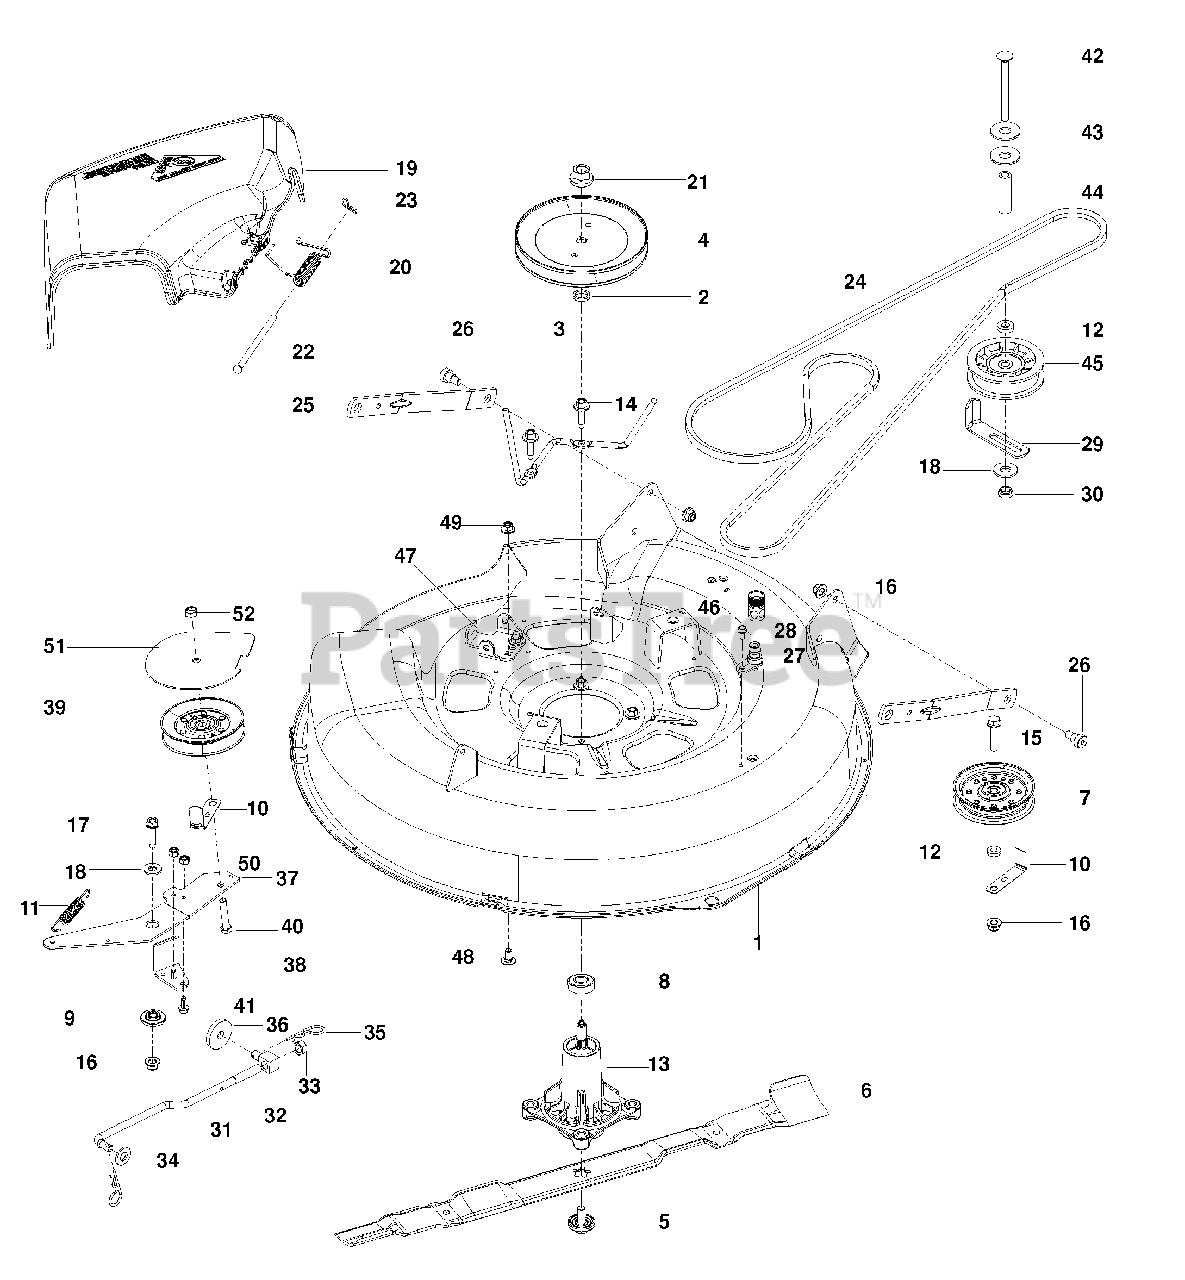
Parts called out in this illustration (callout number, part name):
1	DECK w/ DECALS ORG
2	WASHER/SPACER
3	KEEPER, BELT
4	PULLEY, MANDREL
5	BOLT/WASHER ASSY
6	BLADE, MOWER/MULCH
7	PULLEY, IDLER
8	BEARING, BALL
9	SPACER RETAINER
10	KEEPER, BELT
11	SPRING RETURN
12	WASHER 3/8 x 3/4
13	MANDREL ASSY
14	SCREW 5/16-18 WASHER HD
15	BOLT 3/8-16 x 1 3/4 WHIZLK
16	NUT 3/8-16 FLANGE NYLOC
17	BOLT 3/8-16 x 1 1/2 THD FRM
18	WASHER 3/8 FLT STD
19	CHUTE, DISCHARGE
20	SPRING, TORSION
21	NUT 9/16 TOP CENTER LOCK
22	PIN, CLEVIS
24	BELT, DECK
25	ARM, DECK SUSPENSION
26	BOLT 3/8-16 x 3/8 SKT HD
27	WASHOUT PORT
28	BOLT 1/4-20 x 1/2 HWST
29	GUIDE, BELT
30	NUT 3/8-16 HEX JAM NYLOC
31	LINK, SUSPENSION
33	NUT 7/16-20 HEX NYLOC
34	WASHER 1/2 SAE
36	WASHER 1 3/4 x 1/4 HEAVY
37	ARM, IDLER
38	ARM, LH BRAKE
39	IDLER V-GROOVE
40	HCS 3/8-16 x 1 1/2
41	SCREW 1/4-20 x 5/8 THDROLL
42	RHSNB 3/8-16 x 4
43	WASHER 7/16 FLT
44	SPACER .390 ID x 2 1/4
45	PULLEY, DECK IDLER
46	COUPLING, QUICK DISC
47	BRACKET, DEFLECTOR
48	RHSNB 5/16-18 x 5/8
49	NUT 5/16-18 FLANGE NYLOC
50	NUT 1/4-20 HEX NYLOC
51	COVER, PULLEY
52	NUT 3/8-16 HEX JAM
